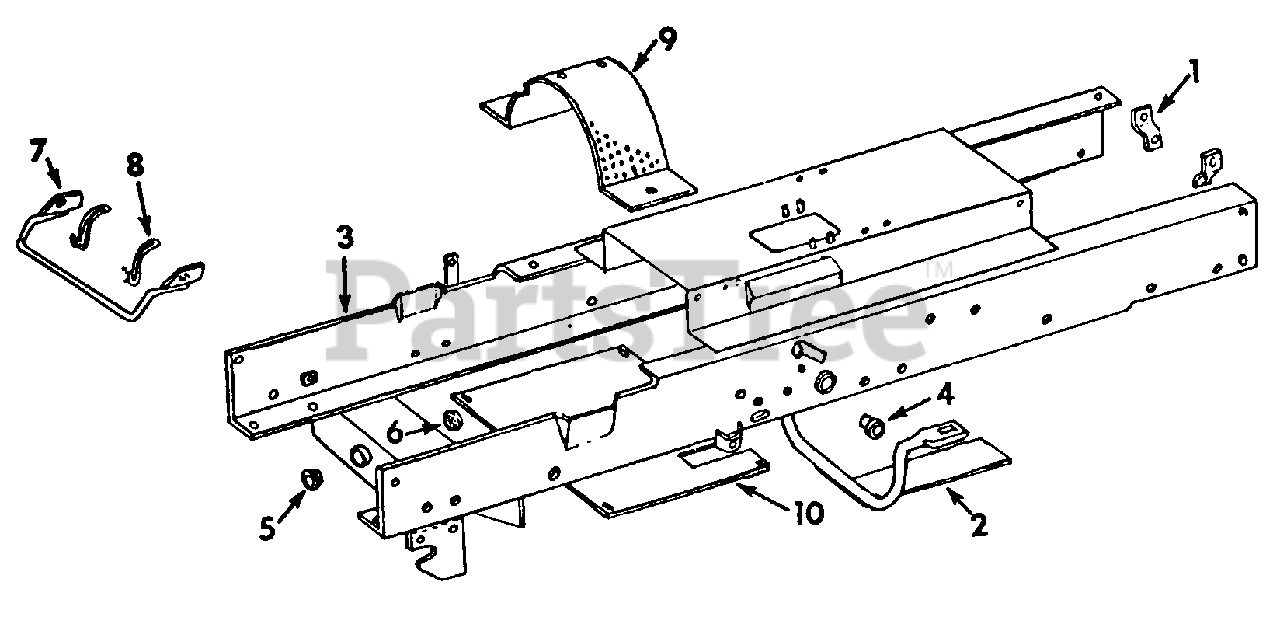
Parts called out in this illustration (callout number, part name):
1	Bracket, Transmission Mounting
2	Guard Assy, Suction Tube
3	Frame Assy
4	Bearing, Clutch Pedal Shaft
5	Bracket, Front Axle Pivot Pin Front
6	Washer, Front Axle Pivot Pin Rear
7	Hitch Assy, Quick
8	Spring, Latch
9	Screen, Air Intake
10	Shield, Bottom Dust
